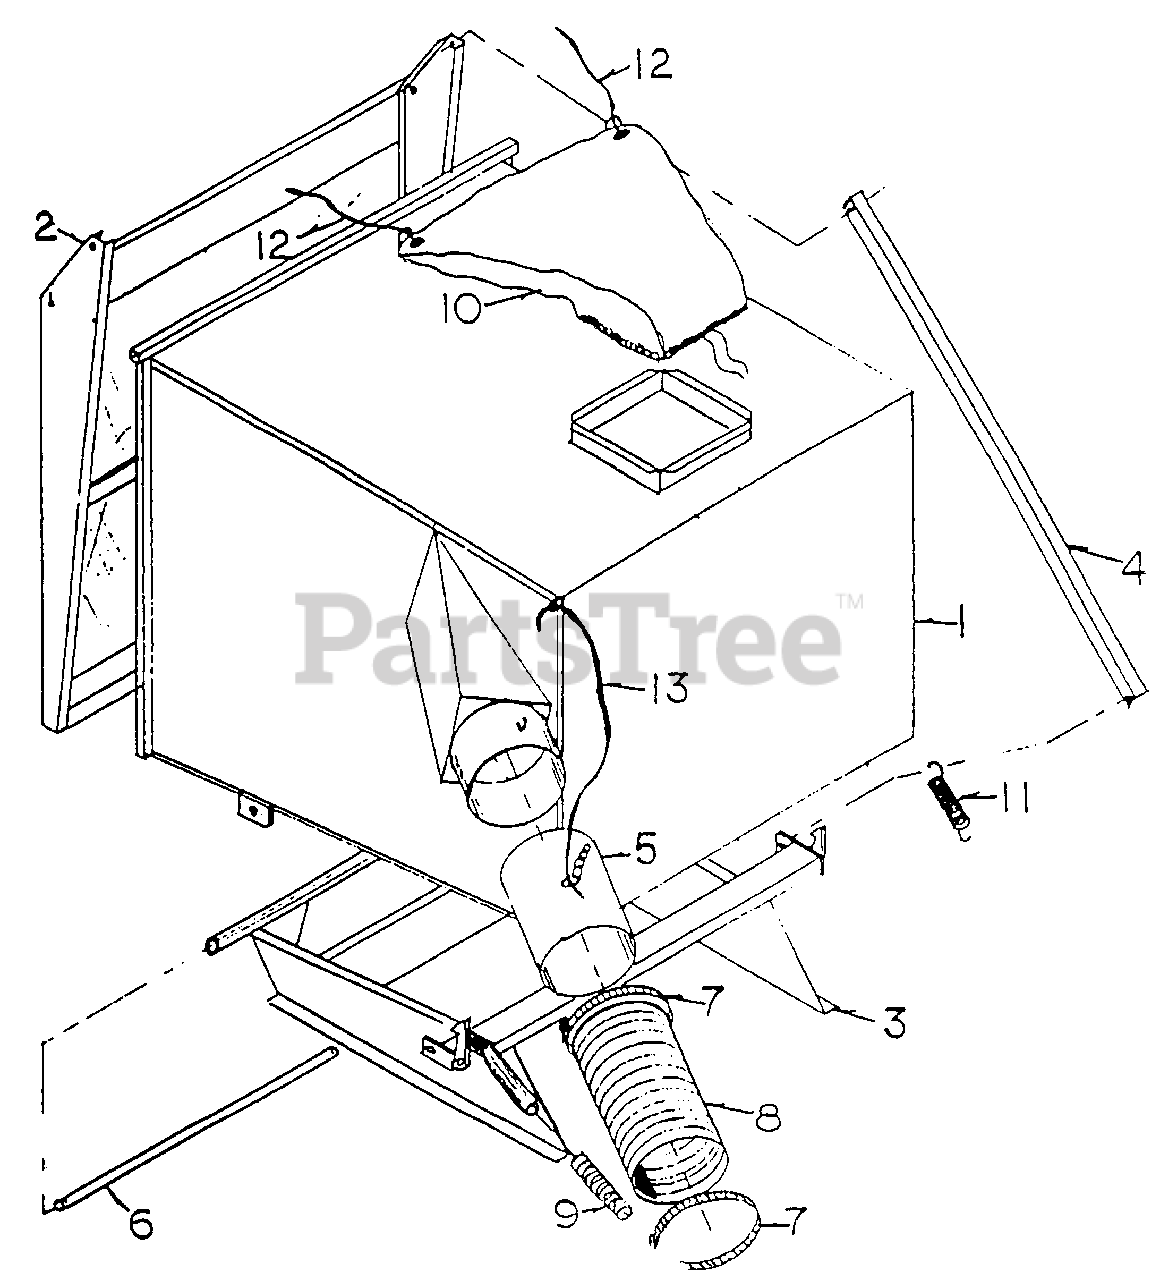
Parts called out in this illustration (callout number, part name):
1	GRASS BOX
3	BOX MOUNT
4	DOOR LINKACE
5	MALE TUBE
8	HOSE
9	HANDLE GRIP
12	BAC ROPE
13	MALE TUBE ROPE
